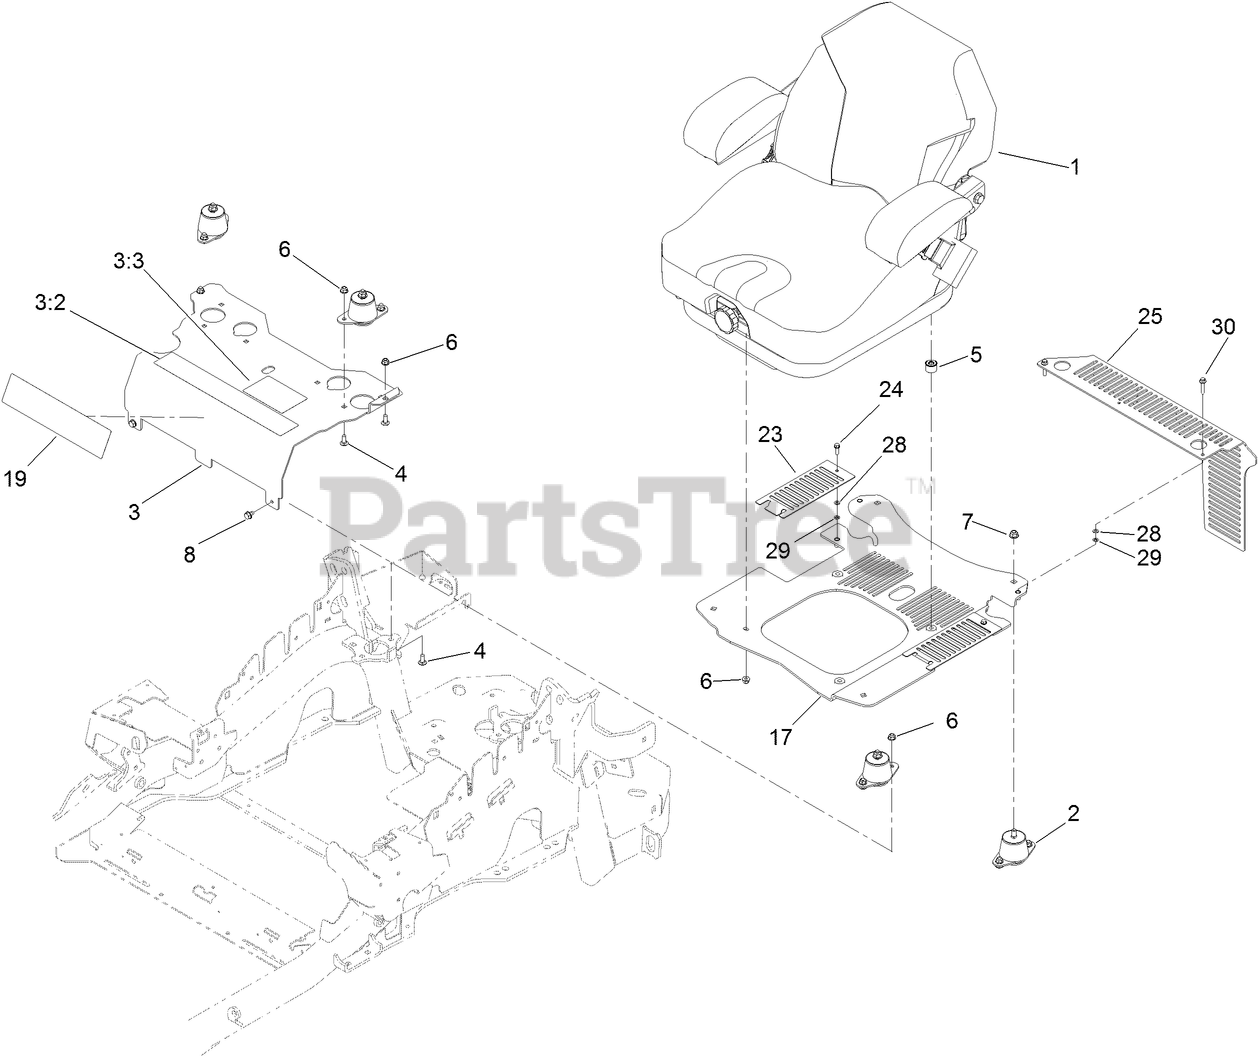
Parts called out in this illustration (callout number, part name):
1	SUSPENSION SEAT ASM
2	ISOLATOR-SEAT
3	MOUNT-SEAT
3:2	DECAL-CONSOLE
3:3	DECAL-SERVICE AID
4	SCREW-CARR
5	SPACER
6	NUT-HF, NI
7	NUT-HF, NI
8	SCREW
17	SEAT BASE ASM
24	SCREW-HWH
25	GUARD-CE
28	WASHER-FLAT
29	NUT-RETAINER
30	SCREW-HHF
